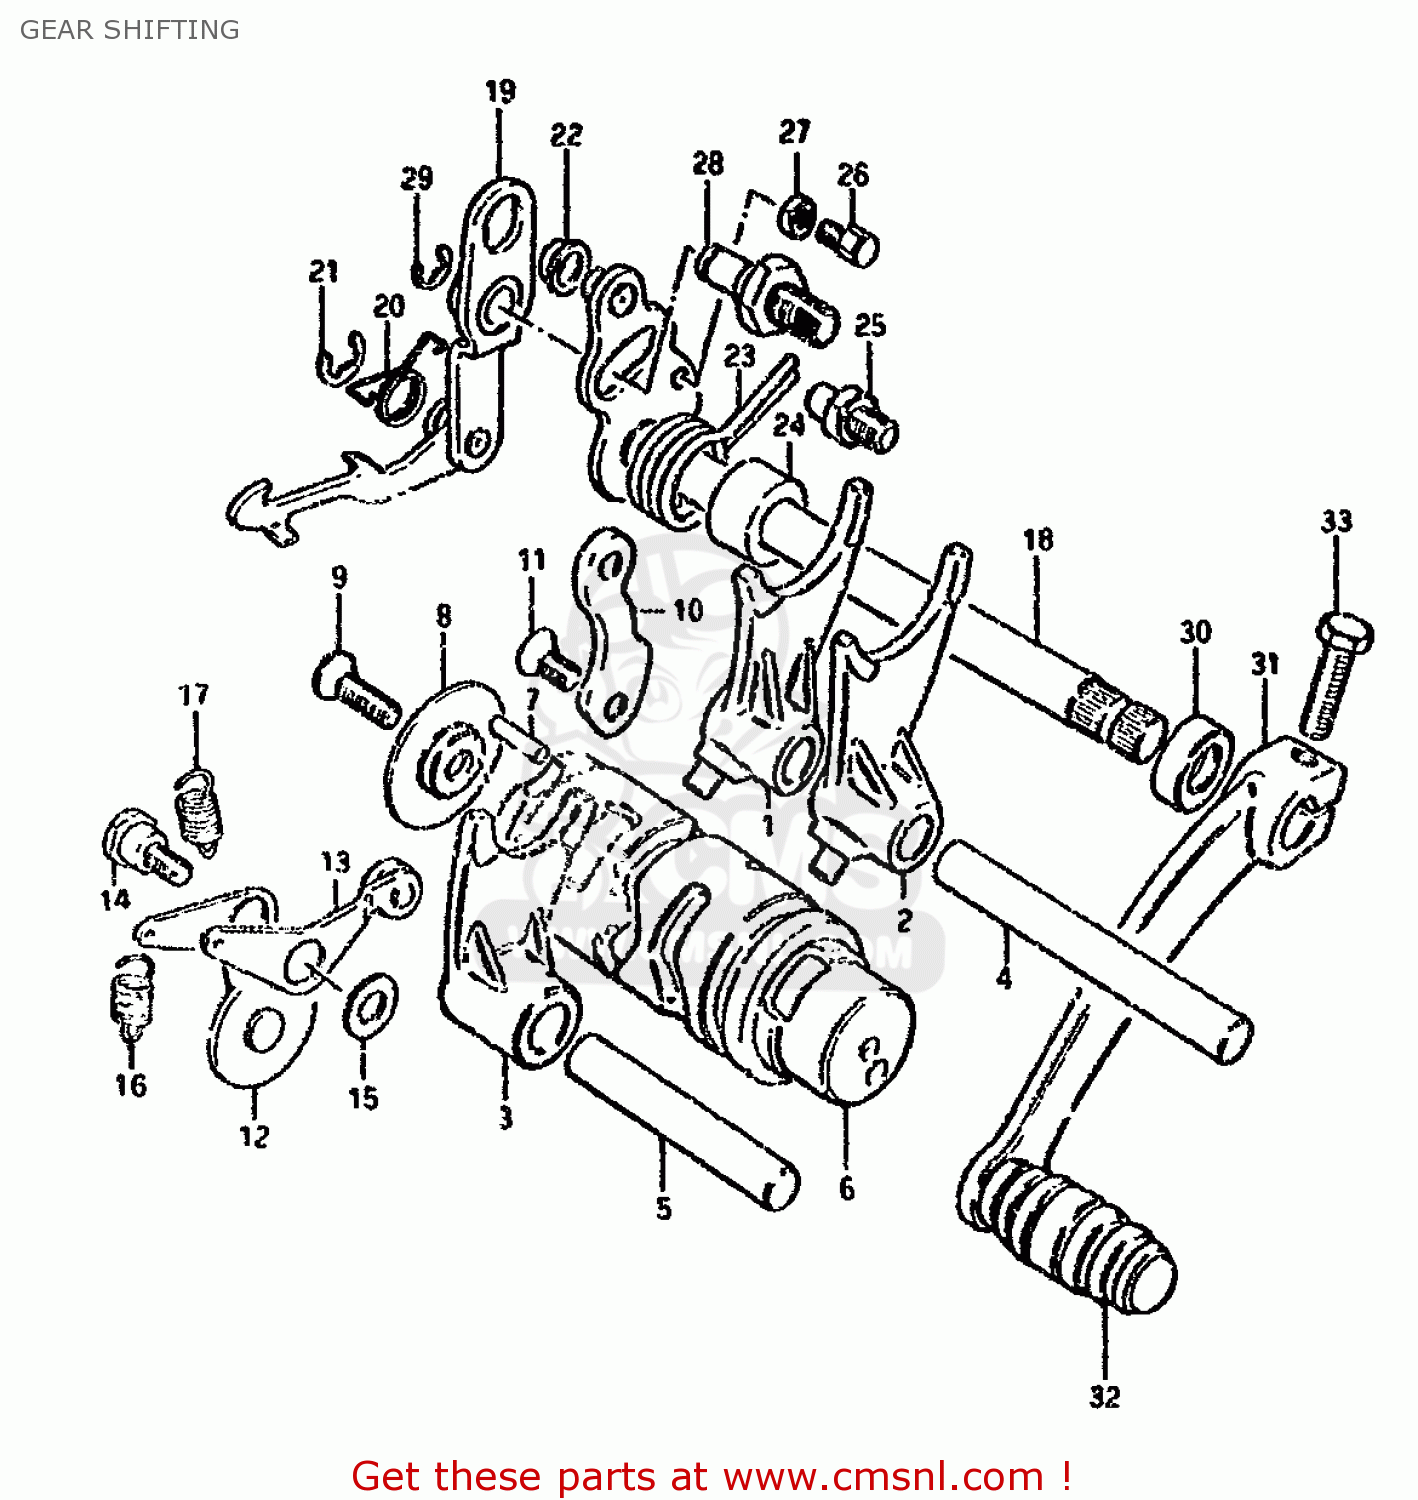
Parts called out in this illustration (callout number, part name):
1	FORK,GEAR SHIFT NO.1
2	FORK,GEAR SHIFT NO.2
3	FORK,GEAR SHIFT NO.2
4	SHAFT,GEAR SHIFT FORK
5	SHAFT,GEAR SHIFT FORK
6	CAM,GEAR SHIFT
7	PIN
8	RETAINER,GEAR SHIFT CAM DR PIN
9	SCREW
10	GUIDE,GEAR SHIFT CAM
11	SCREW
12	STOPPER,GEAR SHIFT CAM
13	STOPPER,GEAR SHIFT CAM NEUTRAL
14	BOLT(6X18.3)
15	WASHER
16	SPRING
17	SPRING
18	SHAFT,GEAR SHIFT
19	PAWL,GEAR SHIFT
20	SPRING
21	E RING
22	SPACER(7X10X5)
23	SPRING
24	SPACER(12X20X15.3)
25	STOPPER,GEAR SHIFT CAM
26	BOLT,GEAR SHAFT RETURN SPR SET
27	NUT
28	STOPPER,GEAR SHIFT CAM
29	E.RING
30	OIL SEAL
31	LEVER ASSY,GEAR SHIFT
32	RUBBER,GEAR SHIFT PEDAL
33	BOLT
